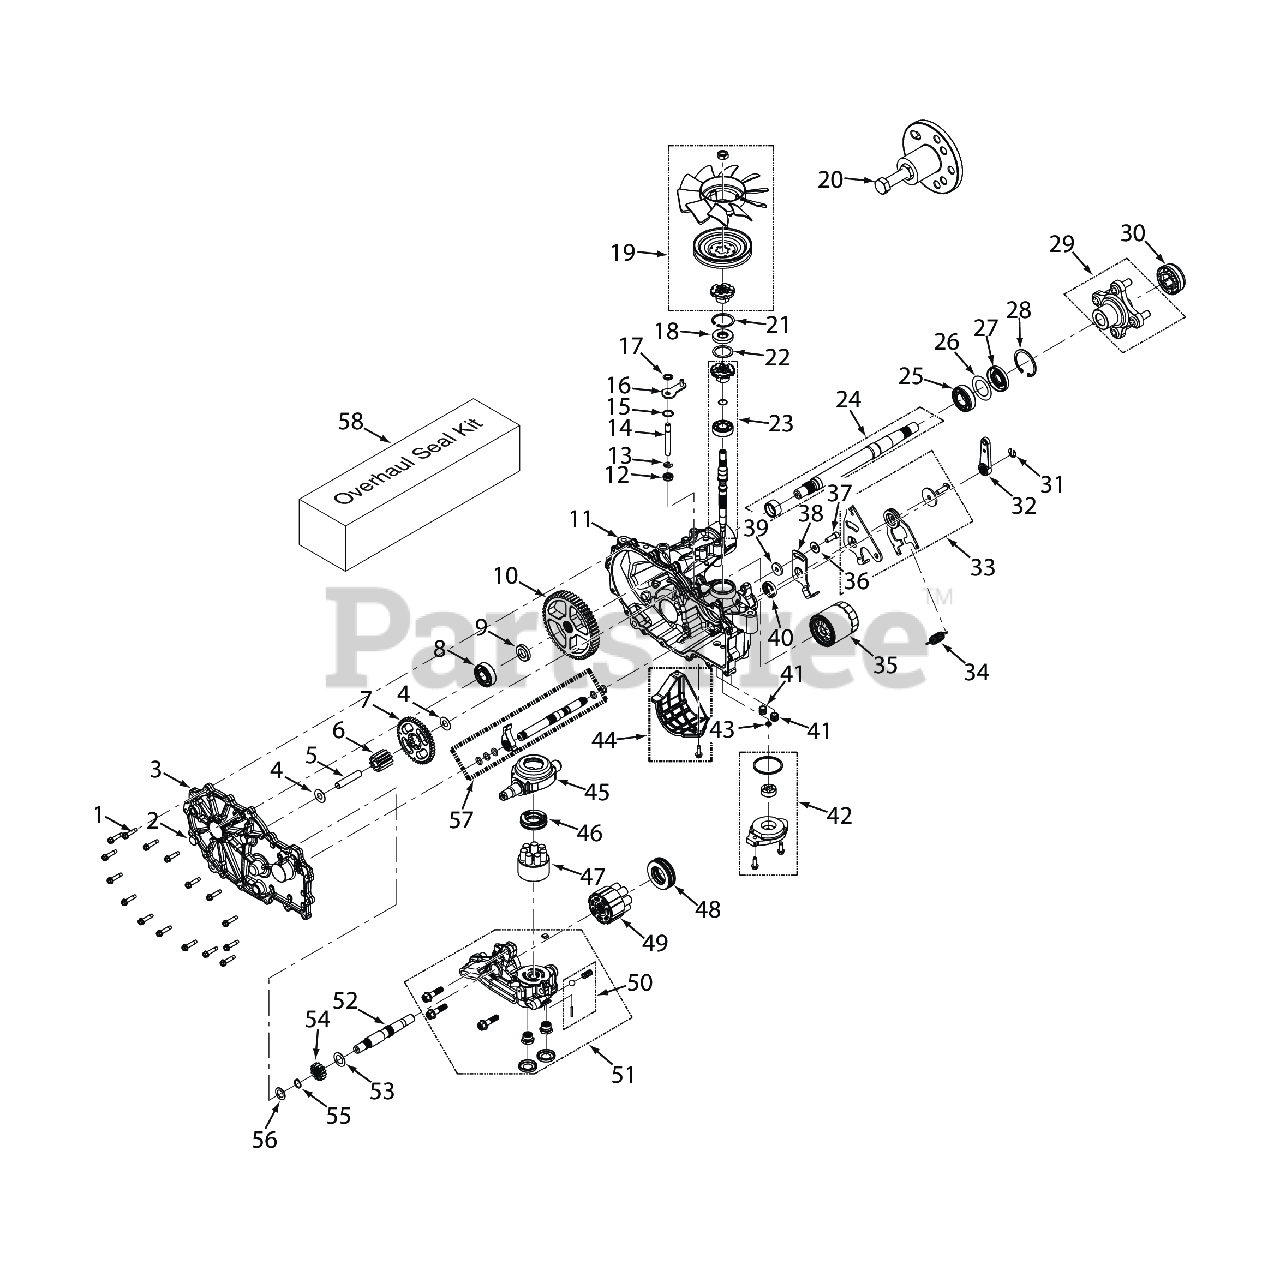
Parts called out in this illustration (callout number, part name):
1	Bolt, Hex Head 1/4-20 x 1-1/8"
2	Plug, External Hex Vent 9/16-18
3	Kit, Side Cover LH
3	Kit, Side Cover RH
4	Washer, .5 x 1.0 x .03
5	Jackshaft Pin
6	Gear, 11T
7	Gear, 45T
8	Kit, Bearing
9	Spacer, .750 x 1.320 x .257
10	Gear, 54T
11	Kit, Housing LH
11	Kit, Housing RH
12	Seal, Lip, .375 x .75 x .25
13	Ring, .Retaining .375 External
14	Rod, By-Pass
15	R i n g , Retaining .750 Internal
16	Arm, Bypass (LH)
16	Arm, Bypass (RH)
17	Ring, Retainging .375 External
18	Seal, Lip 17 x 40 x 7
19	Kit, Fan/Pulley
20	Kit, Hub Puller
21	R i n g , Retaining 2.06 Internal
22	Washer, 1.23 x 1.56 x .04
23	Kit, Input Shaft
24	Kit, Shaft, Axle
25	Bearing, Ball 1.0 x 52 x 15 Open
26	Spacer, 1.355 x 2.035 x .021
27	Seal, Lip TC4 1.0 x 2.06 x .38
28	R i n g , Retaining 2.06 Internal
29	Hub, 4-Bolt
30	Cap, Axle
31	Ring, Retaining External .375"
32	Handle, Brake
33	Kit, RTN Bi-Directional (Right Side)
33	Kit, RTN Bi-Directional (Left Side)
34	Spring, Extension, RTN - 44lbs
35	Filter, Oil
36	Washer, 7/16 x 7/8 OD x .06 HT
37	Bolt, Hex Head Cap Screw 5/16-24 x 1" Patch
38	Arm, Neutral (Left Side)
38	Arm, Neutral (Right Side)
39	Spacer, .32 ID x 1.005 OD x .1495 Thk
40	Seal, Lip 18 x 32 x 7
41	Tube, Charge Triple O-ring
42	Kit, Charge Pump
43	Kit, Gerotor Seal
44	Kit, Filter Guard (LH)
44	Kit, Filter Guard (RH)
45	Trunnion, Swashplate
46	Ball Thrust Bearing
47	Kit, Cylinder Block
48	Thrust Ball Bearing Assembly
49	Kit, 16cc Cylinder Block Assembly (steam
50	Kit, Charge Relief
51	Kit, Charge Relief
51	Kit, Center Section, LH Charge
52	Shaft, Motor
53	Washer, .72 x 1.16 x .04
54	Washer, Flat, .71 x 1.16 x .04
55	Ring, Retaining .625
56	Washer, HT .62 ID x 1.0 OD x .05 Thick
57	Kit, Shaft, Axle
57	Kit, Outboard, RH Rot B / LH Rot A (LH)
58	Kit, Outboard, RH Rot A / LH Rot B (RH)
